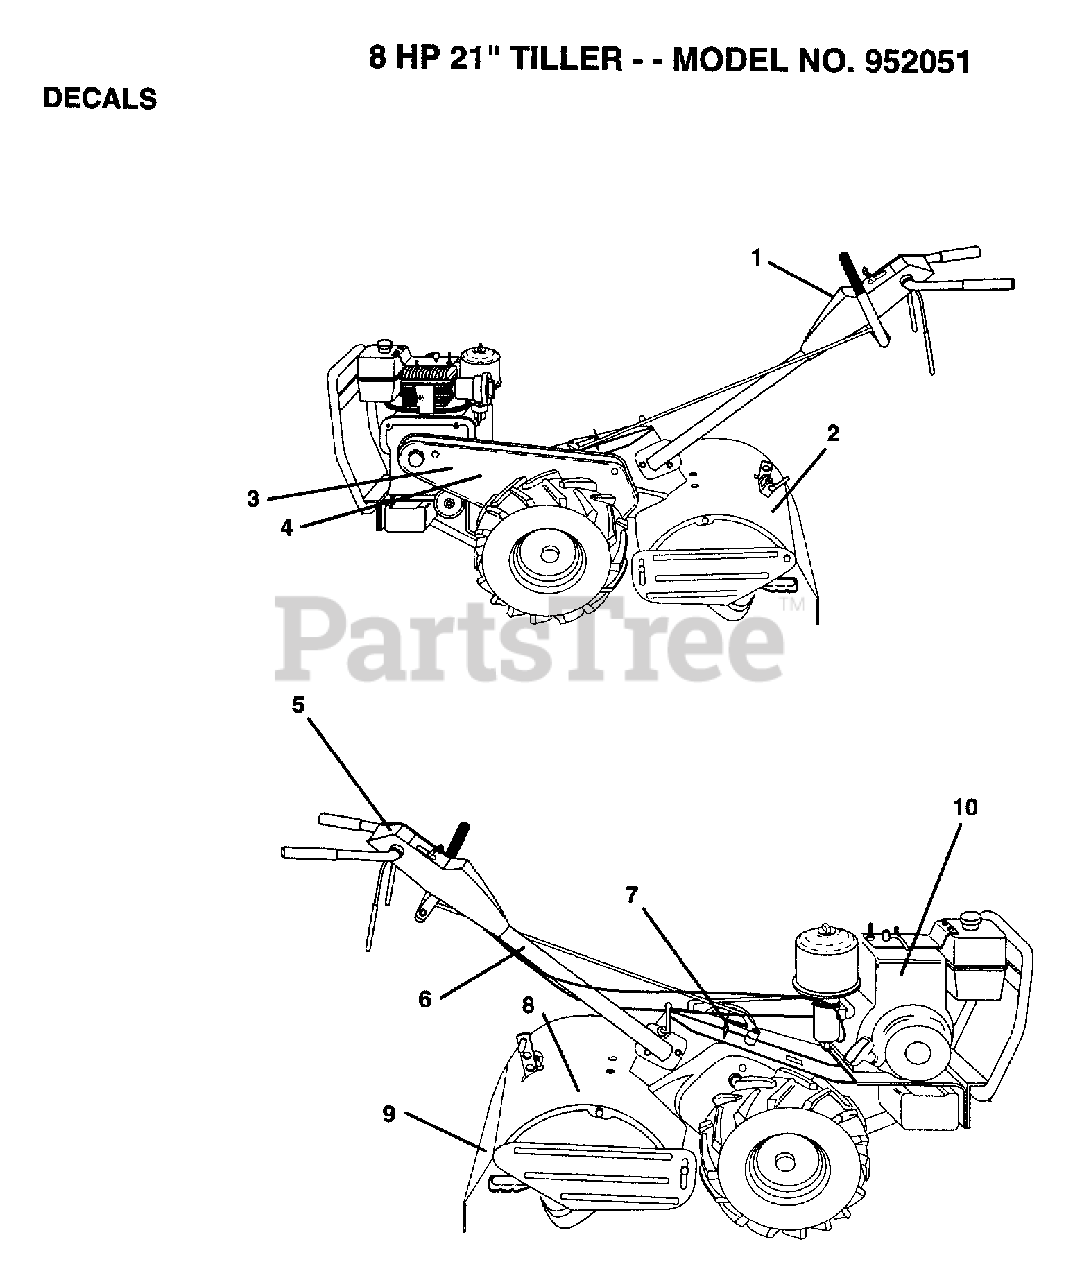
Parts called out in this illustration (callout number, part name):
1	DECAL.PNL.CONTROL
2	DECAL SHIELD TINE
3	DECAL LOGO GUARD
4	DECAL LOGO GUARD
5	DECAL.INST.PNL.CT
6	DECAL TI
7	DECAL.SHIFT.IND.
9	DECAL TI
10	DECAL, BRIGGS & STRATTON
